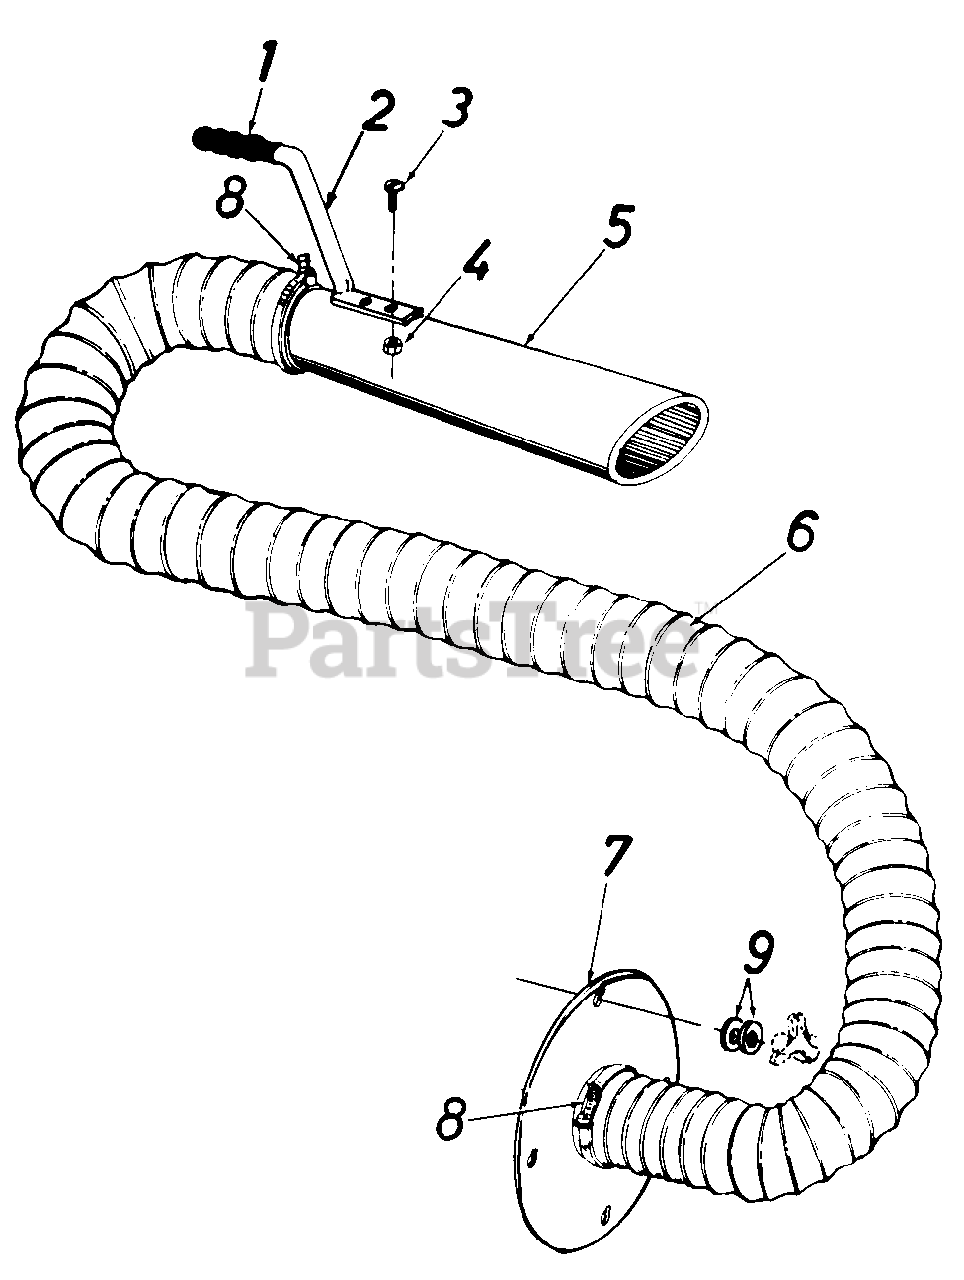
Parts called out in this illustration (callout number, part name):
1	Handle Grip
3	Truss Sems Scr. 10-24 x 1/2" Lg
4	Hex Nut 10-24 Thd.
5	Hose Nozzle
6	Flexible Hose 4" Dia. x 10' Lg.
9	Flat Washer .34 I.D. x 1.12 O.D.
